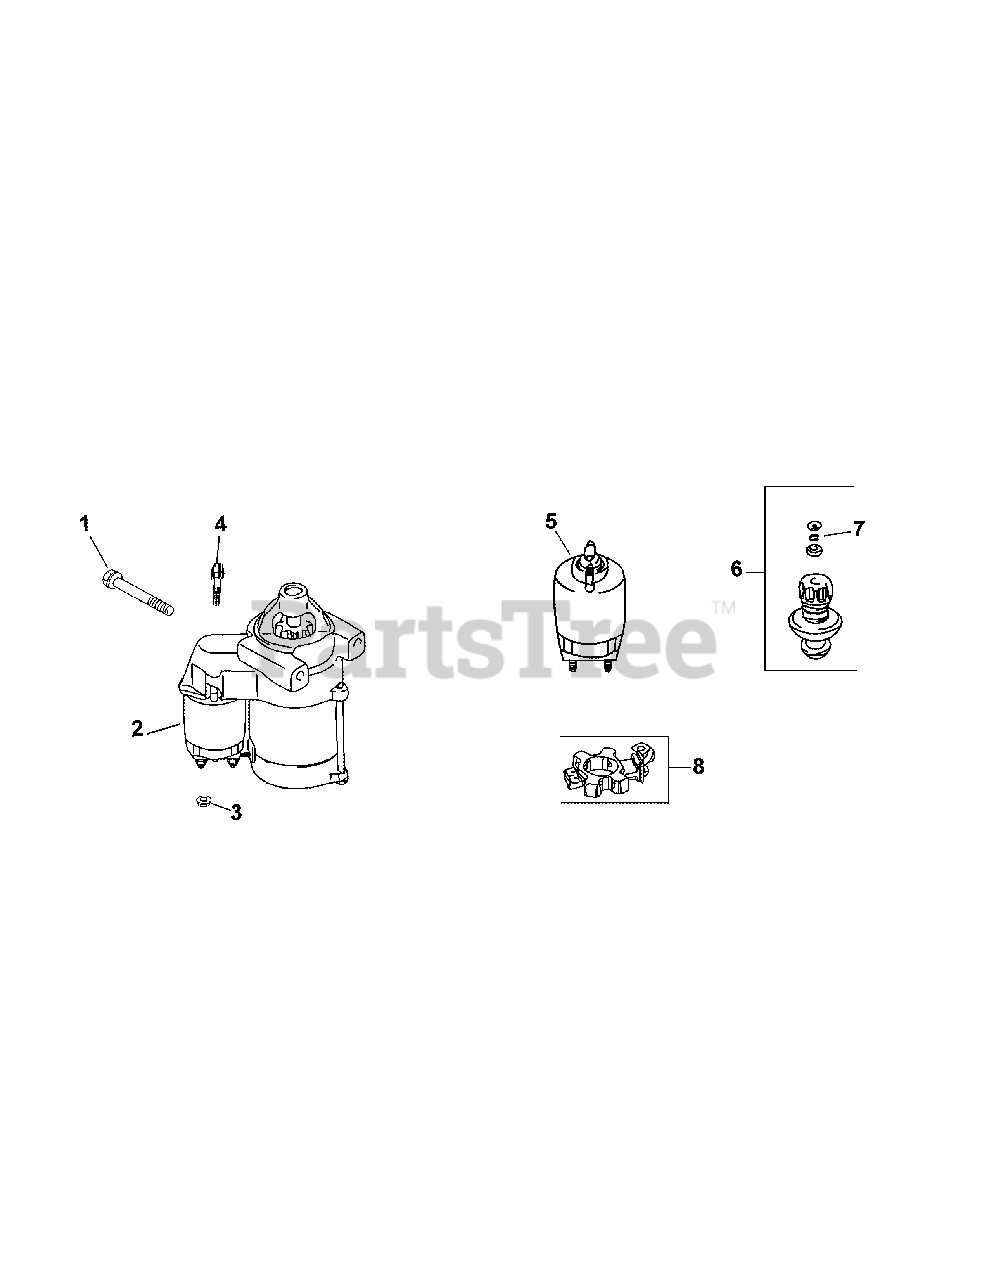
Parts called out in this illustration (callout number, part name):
1	Hex Flange Screw (M8 x 1.25 x 80)
2	Solenoid Shift Starter
3	Hex Flange Nut (M8 x 1.25)
4	External Torx Head Screw
6	Starter Pinion Kit
